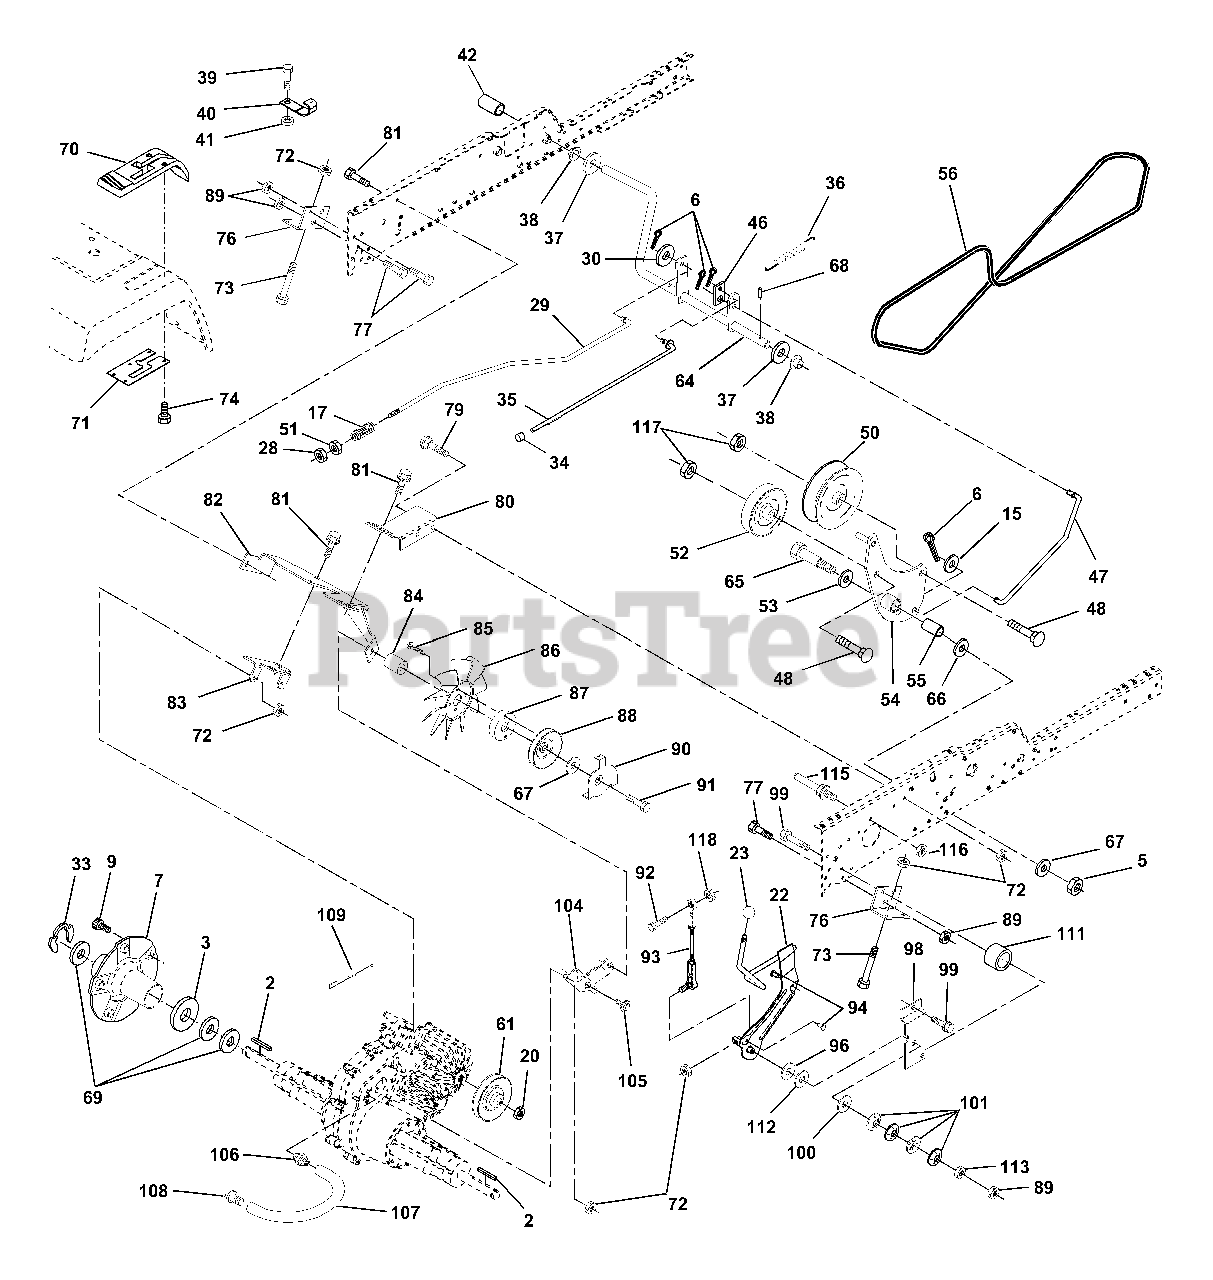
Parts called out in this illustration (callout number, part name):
2	Key 1/4 x 2.5
3	Washer Thrust Axle Harden
5	Nut Crownlock 3/8-16
6	Pin Cotter 1/8 x 3/4
7	Wheel Hub Asm.
9	Bolt Hub
15	Washer 13/32 x 13/16 x 16 Ga.
17	Spring Rod Brake
20	Nut Hex Jam Toplock 1/2-20
22	Shaft Arm Asm
28	Nut, Hex Jam 3/8-16
29	Brake Rod
30	Washer 13/32 x 1 x 16Ga
34	Cap Plunger
35	Rod Parking Brake
36	Spring Drive Ground
37	Washer 25/32 x 1-1/4 x 16 Ga.
39	Screw Fin #10-24 x 1
40	Actuator Interlock Switch
41	Nut Toplock #10-24 UNC
42	Cover Pedal
46	Retainer Spring
47	Clutch Rod
48	Bolt Carriage 3/8-16 x 1-1/2 Gr. 5
50	Pulley Idler Flat
51	Nut Lock Hex 3/8-16
52	Pulley Idler Grooved
53	Washer Hardened
54	Clutch Arm Asm
55	Bearing, Idler
61	Pullery Transaxle
64	Shaft Asm Brake Parking Clutch
65	Bolt Shoulder
66	Washer Hardened
67	Washer 13/32 x 13/16 x 12 Ga
69	Washer
70	Console Hydro Fender
71	Plate Console Shift
72	Nut Crownlock 5/16-18
73	Bolt Hex FLGHD 5/16-18 x 3 Gr 5
74	Screw, Hex Wsh Hi-Lo 1/4-1/2
76	Bracket Transaxle
77	Bolt Fin Hex 7/16-14 x 1
79	Bolt Carriage 5/16-18 x 5/8
80	Bracket Torque RH
81	Screw 3/8-16 x 3/4
82	Bracket Mount Torque/Fan
83	Strap Torque Mid
85	Screw #10-24 x 1-1/4
86	Fan 7" Hydro
87	Adapter Fan
88	Pulley Idler
89	Nut, Crownlock 7/16-14
90	Keeper Belt
91	Screw Thdrol 3/8-16 x 2-3/4
92	Bolt Fin Hex 5/16-18 x 1.75
93	Link Shift Asm
94	Fastener Christmas Tree
96	Washer Nickel Plated
98	Bracket Shift
99	Screw 3/8-16 x 1-1/2
100	Washer Compression
101	Washer Bellville
104	Bracket Idler
105	Screw Tap 1/4-20 x 1/2
106	O-Ring Asm. Hydro Gear
107	Line Fuel Hydro
108	Cap Vent
109	Spring Return Brake
111	Spacer Shift Lever VGTH
112	Washer Nylon High Temp
113	Nut Hex ASF 7/16-14 UNC
115	Keeper Belt Grid Dr.
116	Nut Lock Hex Flange 5/16-18
117	Nut Lock Flg. 3/8-16 UNC
118	Nut Lock Hex w/Ins. 5/16-18 Unc
